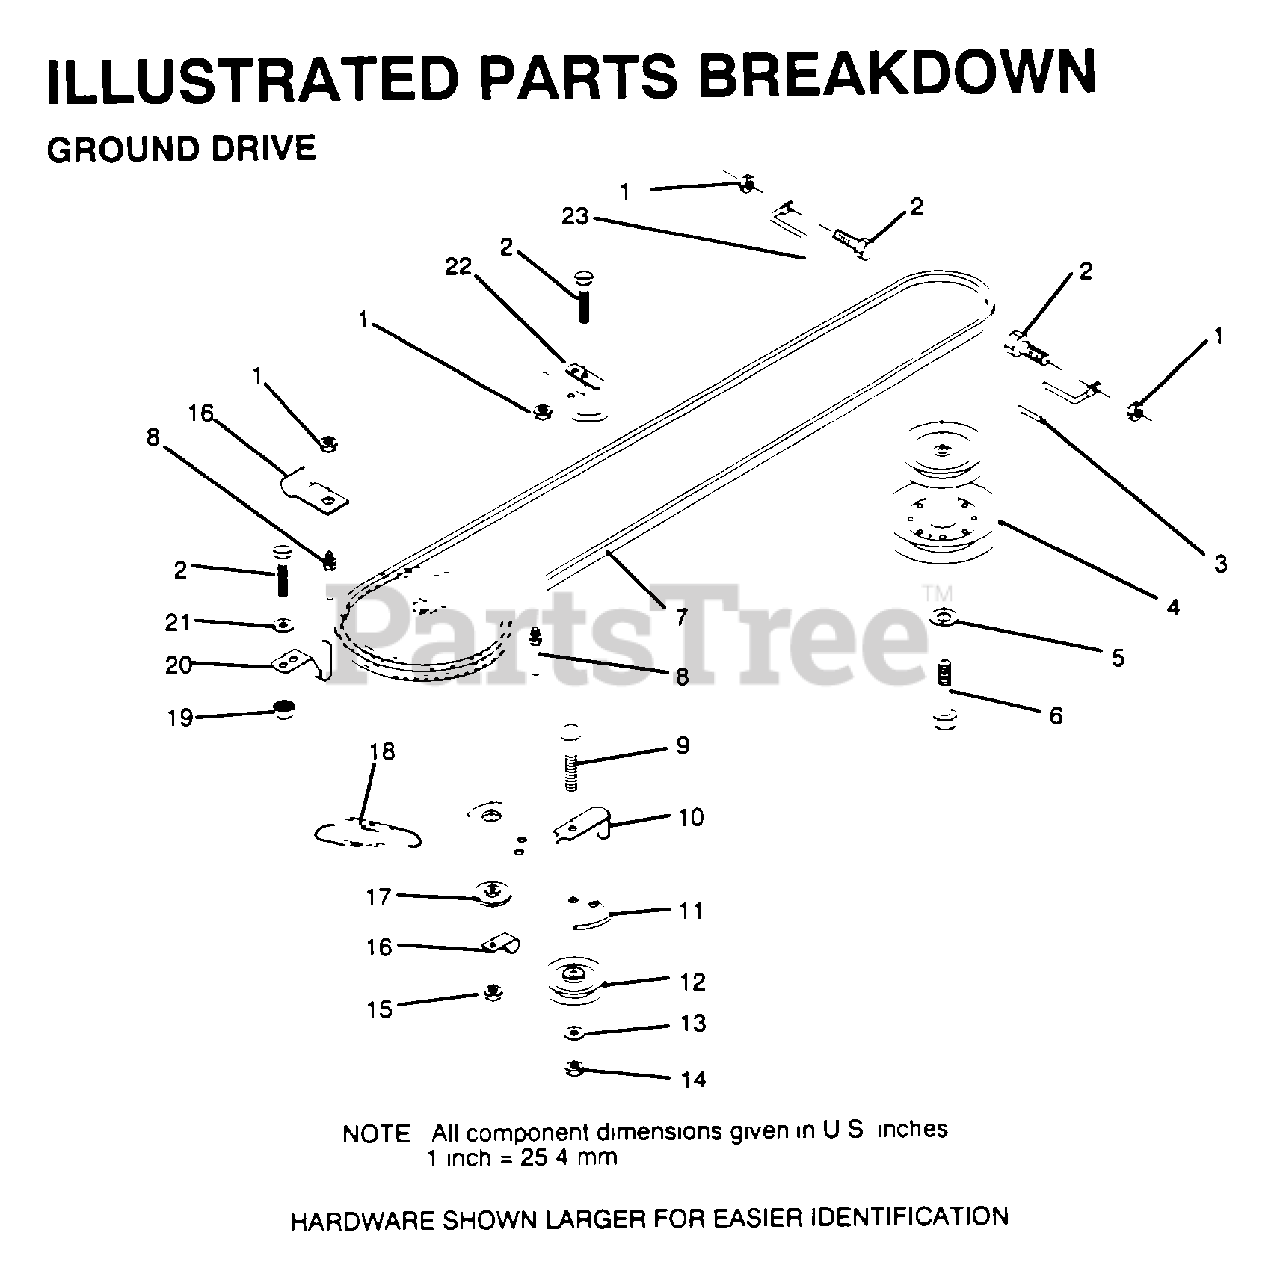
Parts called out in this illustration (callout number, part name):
2	BOLT
3	KEEPER ENG BEL LH
5	LOCKWASHER
6	BOLT
7	BELT
8	"KEEPER,DRIVE BELT"
9	BOLT
10	"KEEP,IDLER DR BEL"
12	PULLEY.IDLER.FLAT
13	WASHER
14	LOCKNUT
16	"CLIP,INSULATOR"
17	SPACER RETAINER
20	"KEEPER,DR BELT "
21	WASHER
22	"KEEPER,FRA DR BEL"
23	KEEPER ENG DR RH
